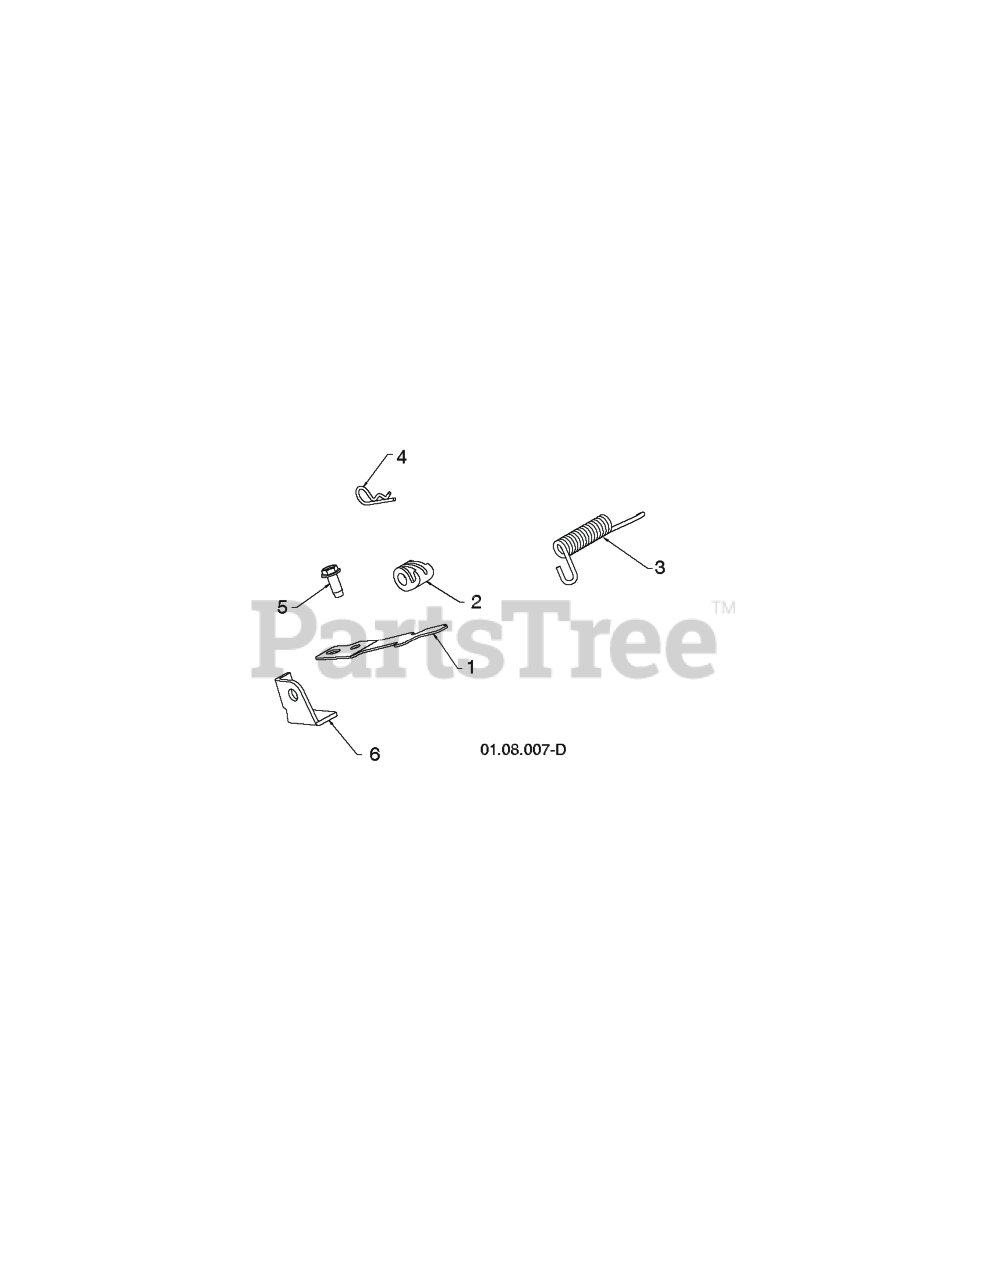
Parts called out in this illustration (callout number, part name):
1	SPRING.INTERLOCK
2	CAM.INTERLOCK.RELEASE
3	SPRING.TORSION.LEVER
4	SPRING RETAINER
5	SCREW 14-20 X 5/8
6	STOP.INTERTLOCK
